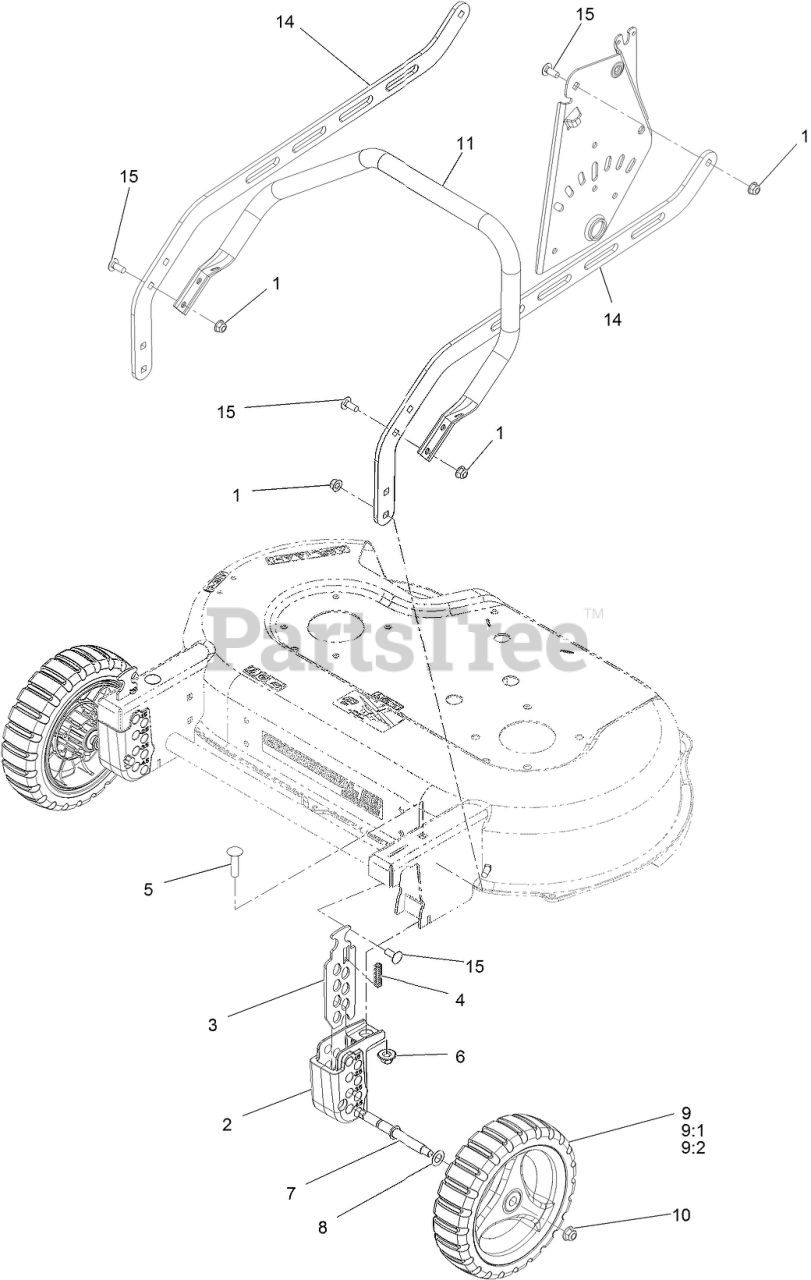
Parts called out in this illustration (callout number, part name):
1	NUT-HF, NI
2	BLOCK-FRONT QUADRANT
3	PLATE, FRONT HEIGHT
4	SPRING-COMPRESSION
5	SCREW-CARR
6	Nut-Nyloc 3/8-16 Flg
7	AXLE-WHEEL
8	WASHER-PLAIN
9	WHEEL ASM, 9" W/BEARINGS
9:1	WHEEL ASM, 9"
9:2	BEARING-BALL
10	NUT-HF, NI
11	GUARD-ENGINE
15	SCREW-CARR
